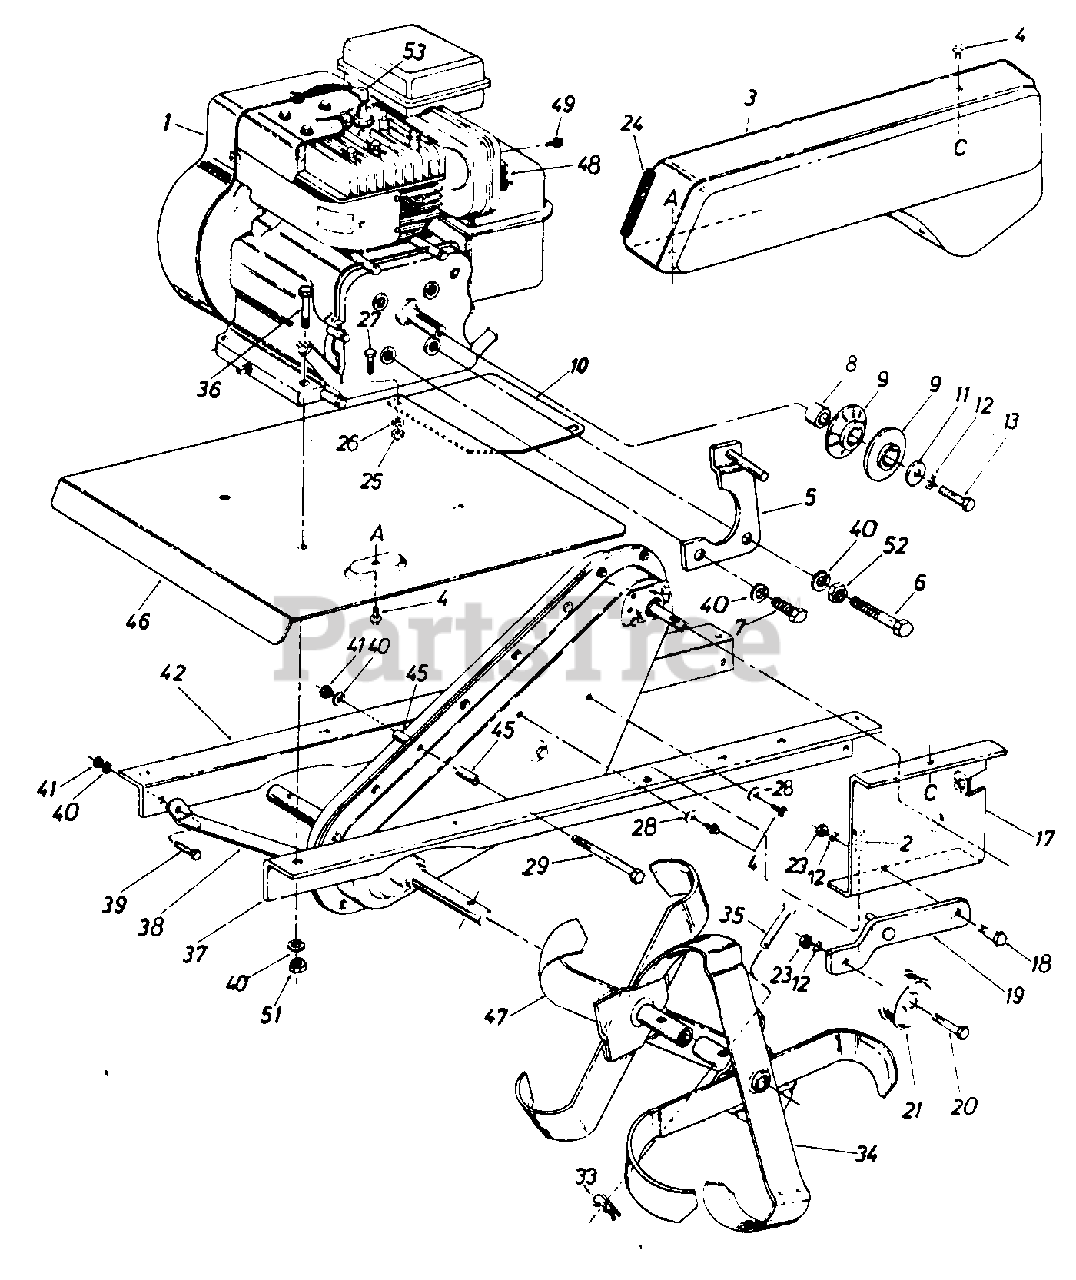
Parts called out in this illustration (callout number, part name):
1	Engine
2	Hex Self-Tap Scr. 5/16-24 x .5"
3	Belt Cover
4	Hex Self-Tap Scr. 1/4-20 x .5"
5	Belt Keeper Brkt. Ass'y.
6	Hex Bolt 5/16-24 x 2.25" Lg. (Grade 5)
7	Hex Bolt 5/16-24 x .62" Lg. (Grade 5)
8	Spacer
9	Pulley Half
10	Tine Shield Extension
11	Fl-Wash. 3/8" I.D. x 1.25"
12	L-Wash. 3/8" I.D.
13	Hex Bolt 3/8-24 x 1.00" Lg.
17	Idler Mounting Brkt.
18	Shld. Bolt
19	Idler Bracket Ass'y.
20	Hex Bolt 3/8-16 x 1.5" Lg.
21	Idler Pulley
23	Hex Jam Nut 3/8-16 Thd.
24	Trim Strip-3"
25	Hex Nut 1/4-20 Thd.
26	L-Wash. 1/4" I.D.
27	Hex Bolt 1/4-20 x .62 Lg.
28	Bell-Wash. .26 I.D. x .75 O.D.
29	Hex Bolt 5/16-18 x 3" Lg.
33	Hairpin Coter
34	See Tine Chart
35	Clevis Pin
36	Hex Bolt 5/16-18 x 1.5" Lg.
37	Frame Rail-L.H.
38	Front Brace Brkt.
39	Hex Bolt 5/16-18 x .75" Lg.
40	L-Wash. 5/16" I.D.
41	Hex Cent. L-Nut 5/16-18 Thd.
42	Frame Rail-R.H.
45	Spacer
46	Tine Shield
47	See Tine Chart
49	Hex Self-Tap Scr. #8-32 x .38" Lg.
51	Hex Nut 5/16-18 Thd.
52	Hex Nut 5/16-24 Thd.
53	Spark Plug Boot
